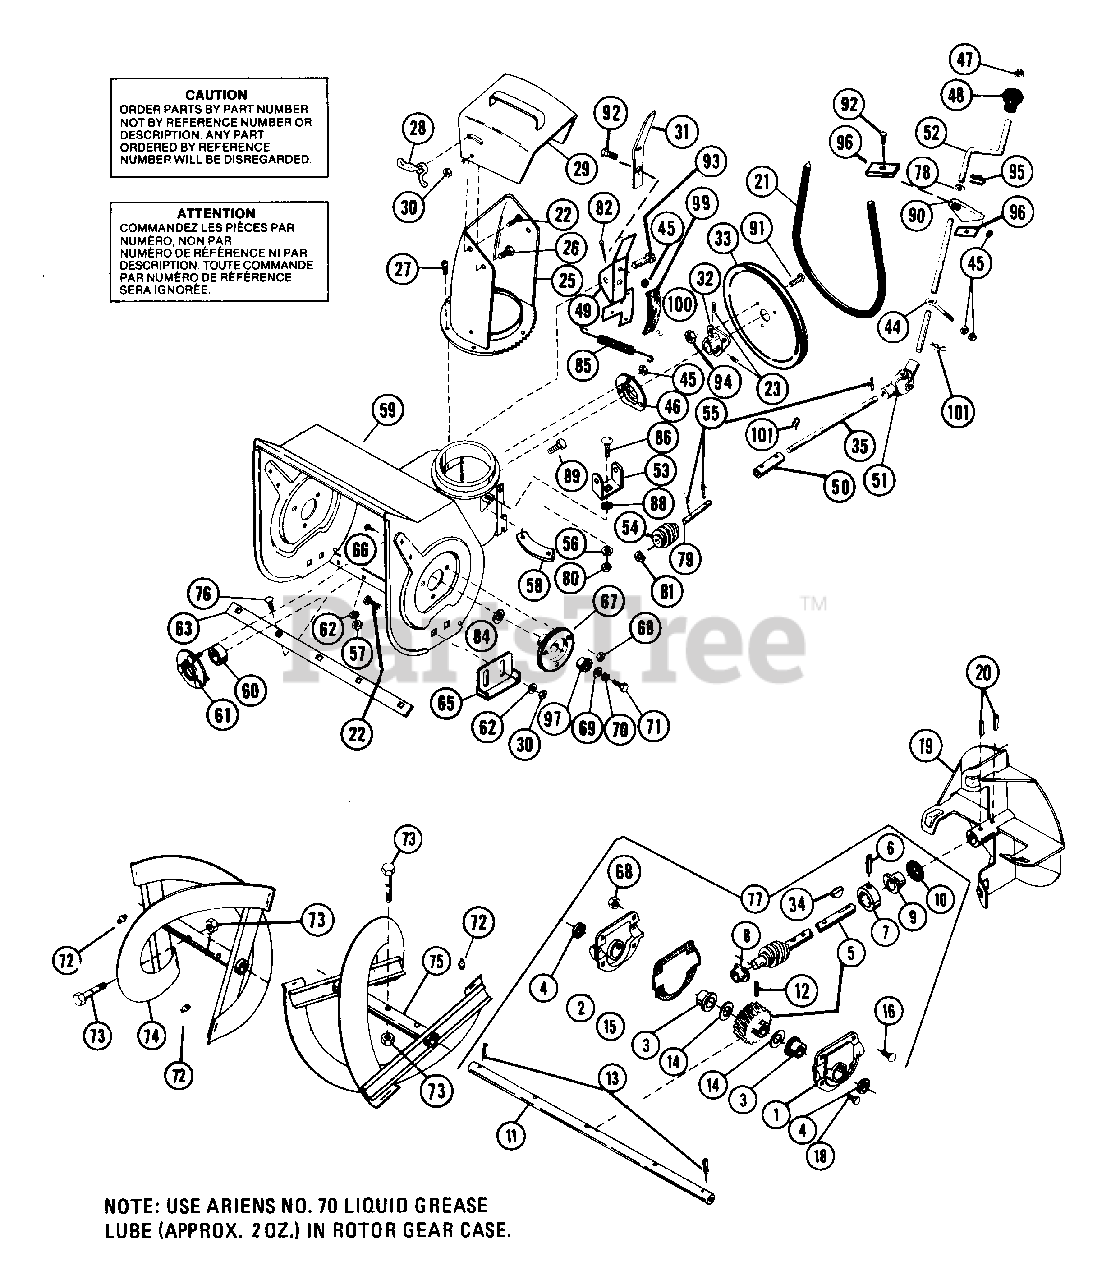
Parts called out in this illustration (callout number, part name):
1	GEAR CASE HALF L H
2	GEAR CASE HALF R H
3	BSHG-FLG1.000X1.12X.62X1.50BR
4	SEAL 1.000X1.312X.150
5	WORM SHAFT & GEAR ASSY
6	PIN-GRV .188X1.25 TP A
7	THRUST COLLAR
8	BSHG-FLG .500X.750X.750X1.000
9	BSHG-FLG .750X1.000X.750X1.250
10	O-RING .250X.943X.103
11	SHAFT, RAKE - 24"
12	PIN-GRV .313X1.32 TP C
13	PIN-ROLL .188X1.50
14	WSHR-HRD-THRS 1.007X1.542X.062
16	BLT-RDHDSQNK .25-20X.88 PL
17	WSHR-FL-STL 1.010X1.505X.062PL
18	BLT-SCRHFWH .38-16X.50 PL
19	FAN - 12"
20	PIN-ROLL .250X1.75
21	V-BELT, 4L-RAW EDGE
22	BLT-RDHDSQNK .38-16X.75 SHT PL
23	SCR-SET .25-20X.38 SKHCUPNL OH
25	DISCHARGE CHUTE
26	BLT-HEX .38-16X.75 PL GR2
27	SCR-TAP 10-24X.375 HWH PL TR
28	WING NUT
29	SERVICE DEFLECTOR ASSM
30	NUT-LK-CTR .375-16 GR A PL
31	ARM EXTENSION
33	PLY-V 9.0 X 1.25 3BLT
34	KEY-WDRF .188X.875X.375 SAE11
44	EYEBOLT
45	NUT-LK-CTR .250-20 PL
46	BEARING FLANGE
47	CAP, 3/8 ROD YWZC
49	BRAKE ARM ASSEMBLY
50	SLEEVE CONNECTOR
51	UNIVERSAL JOINT ASSY
52	CRANK, CHUTE
53	WORM CLEVIS
54	WORM GEAR
55	PIN-ROLL .125X.75
56	WSHR-LK .313X.062
57	NUT-LK .312-18 GR A PL
58	CHUTE CLAMP
59	24 IN BLOWER HOUSING ASSY
60	BRG-BALL .750X1.750X.50
61	BEARING FLANGE
62	WSHR-FL-STL .38X.875X.083 PL
63	SCRAPER BLADE 24"
65	RUNNER
66	BLT-SERNK SL .25-20X.50 PL
67	BEARING SUPPORT
68	NUT-LK-FLG .250-20 PL
69	WSHR-FL-STL .511X1.441X.125 PL
70	WSHR-LK .500X.151 HVY PL
71	BLT-HEX .50-13X1.00 PL GR2
72	SPIN DRIVE ZERK FITTING
73	SHEAR BOLT SERVICE ASSEMBLY
74	RAKE, RIGHT-24"(1ID X 14.75OD)
75	RAKE, LEFT-24"(1ID X 14.75OD)
76	BLT-RDHDSQNK .312-18X.62 PL
77	GEAR CASE - 24" - ALUMINUM
78	WSHR-FL-STL.406X.812X.065PL
79	WORM SHAFT
80	NUT-HEX .312-18
81	WAVE WASHER .406X.750X.063FH
82	PIN-HAIR INT .06X.18X.77
84	WSHR-FL-STL 1.010X1.505X.062PL
85	SG-TENS .062X.56X8.0 WLD 11
86	BLT-RDHDSQNK .31-18X.75 GR5 PL
88	WSHR-LK-EXT .313X.030 PL
89	BLT-SCRHFWH .38-16X.75 PL
90	ROD HANGER
91	BLT-SERRDHD SL .31-18X.75 YZ
92	BLT-HEX .25-20X.50 PL GR2
93	CLEVIS PIN
94	NUT-FLG. .312-18 PL
95	PIN-HAIR INT .08X.18X1.18
97	BSHG-FLG 1.000X1.12X.62X1.50BR
99	BRAKE LINING
100	RVT-TBLR .187X.375 OH ST PL
101	PIN-HAIR INT .08X.38X1.42 YWZC
